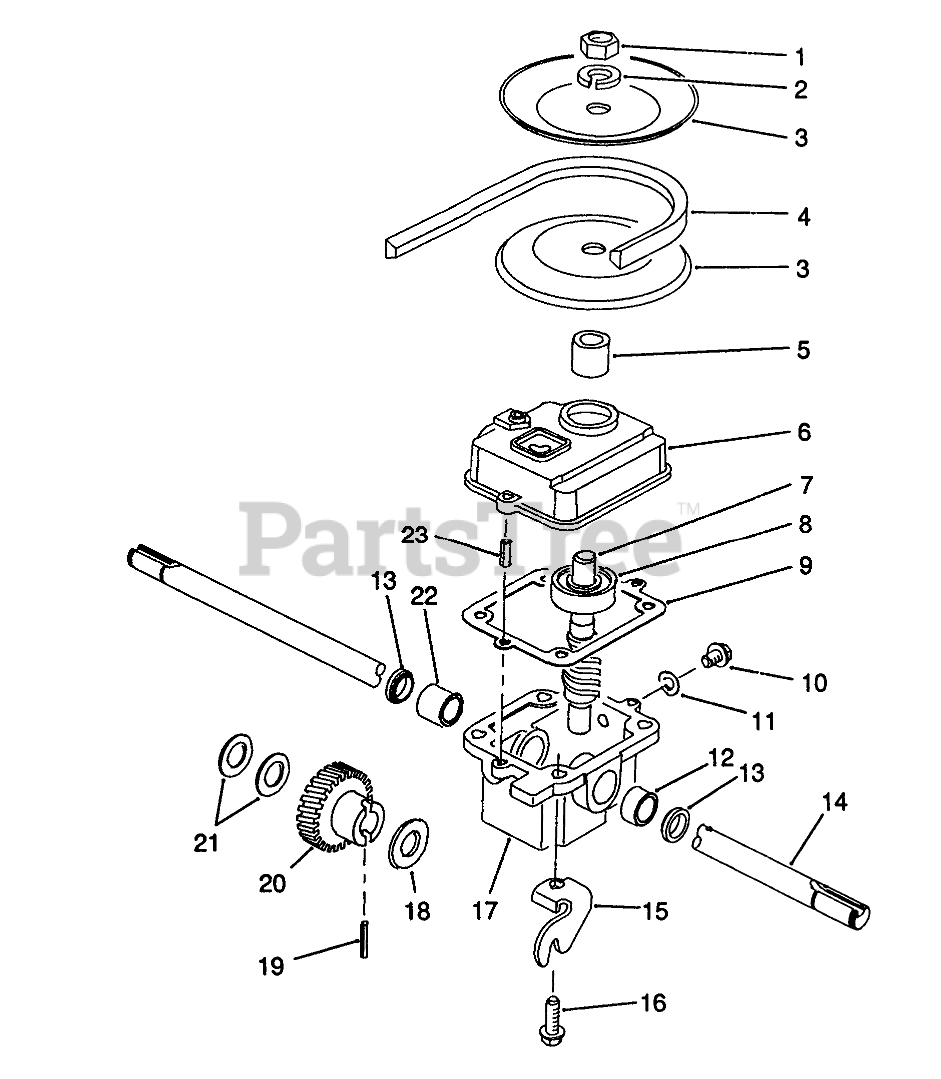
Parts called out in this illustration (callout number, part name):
1	NUT-JAM
2	WASHER-LOCK
3	PULLEY-DRIVEN HALF
4	V-BELT
5	SPACER - PULLEY
6	GEAR CASE COVER
7	SHAFT - WORM
8	BEARING
9	GASKET
10	NYLON SCREW
11	FILL PLUG GASKET
12	BUSHING
13	SEAL-OIL
14	OUTPUT SHAFT
15	TRACTION BRACKET
16	SCREW-HWHTF
17	GEAR CASE
18	THRUST WASHER
19	PIN-SPRING
20	GEAR - HELICAL
21	WASHER-PLAIN
22	BUSHING
23	3/16 X 1/2 ROLL PIN
